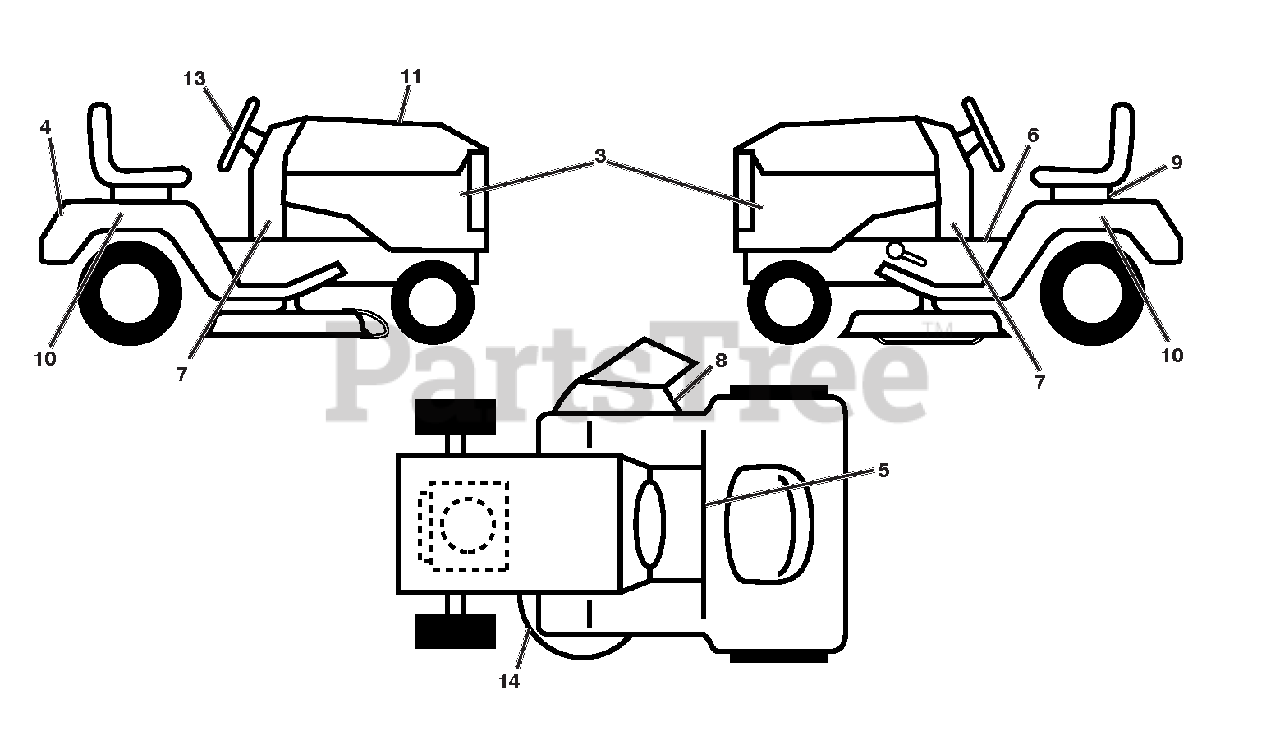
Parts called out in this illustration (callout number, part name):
3	DECAL.SDPNL.PWRDBY KOHL.ARIENS
4	DECAL.FENDER.REAR.ARIENS
5	DECAL.FENDER
6	DECAL.WARNING.START
7	DECAL.DASH.LWOWER.20HP.ARIENS
8	DECAL.WARNING.KEEP.HAND.AWY
9	DECAL.BAT.DAN/POI P/L SYM.WPN
10	DECAL.FENDER.SIDE.HYDRO.ARIENS
11	DECAL REPLACEMENT
13	DECAL.WHEEL.STEER.ARIENS
14	DECAL.V-BELT.SCH.
